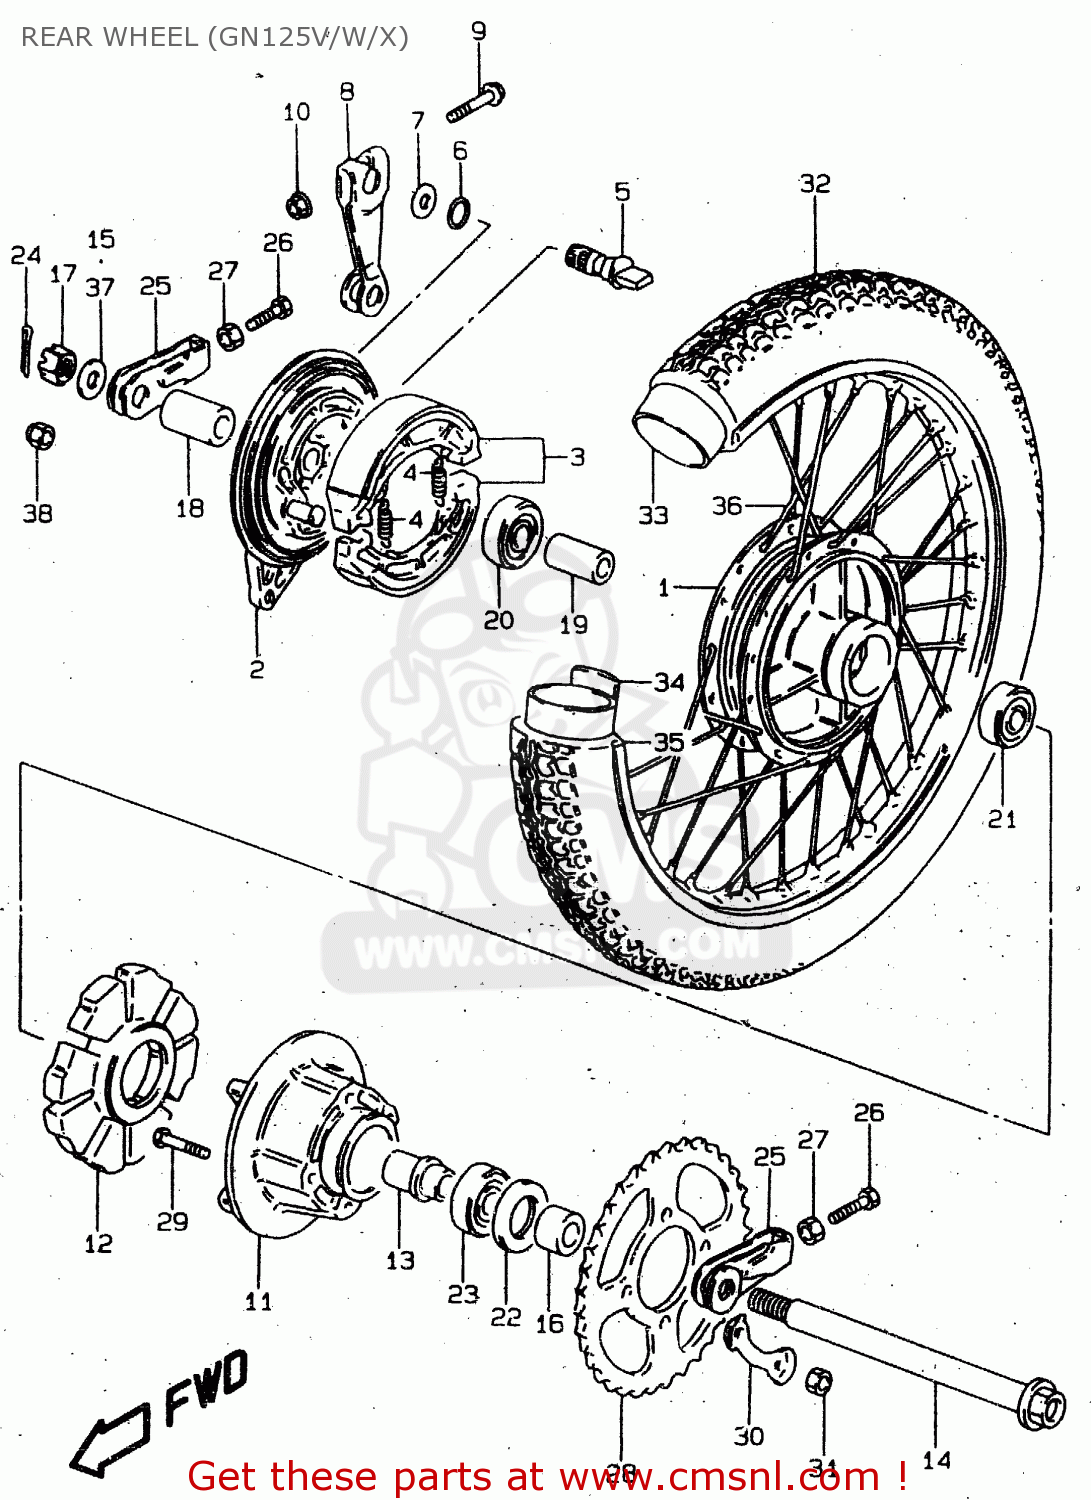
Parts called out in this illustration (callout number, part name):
1	HUB,RR WHEEL
2	PANEL,RR BRAKE ANCHOR
3	SHOE SET,BRAKE (NAS)
4	SPRING(L:34)
5	CAM,BRAKE
6	O RING(D:2.5,ID:13.8)
7	WASHER(14.5X22X1.6)
8	LEVER,RR BRAKE CAM
9	BOLT
10	NUT
11	DRUM,RR SPROCKET MOUNTING
12	ABSORBER ASSY,HUB SHOCK
13	RETAINER,RR SPROCKET DRUM
14	AXLE,RR
15	WASHER
16	SPACER(15X28X19)
17	NUT
18	SPACER(15.2X26X33)
19	SPACER(15.3X21.7X63)
20	BEARING
21	BEARING
22	SEAL,OIL(28X47X7)
23	BEARING(20X47X14)
24	COTTER PIN
25	ADJUSTER,CHAIN
26	BOLT(8X50)
27	NUT
28	SPROCKET,RR(NT:42)
29	BOLT
30	WASHER
31	NUT
32	TIRE,RR(3.50-16 4PR)
33	TUBE
34	PROTECTOR,INNER TUBE
35	RIM,RR WHEEL(185X16)
36	SPOKE ASSY,RR WHEEL
37	WASHER
38	NUT
